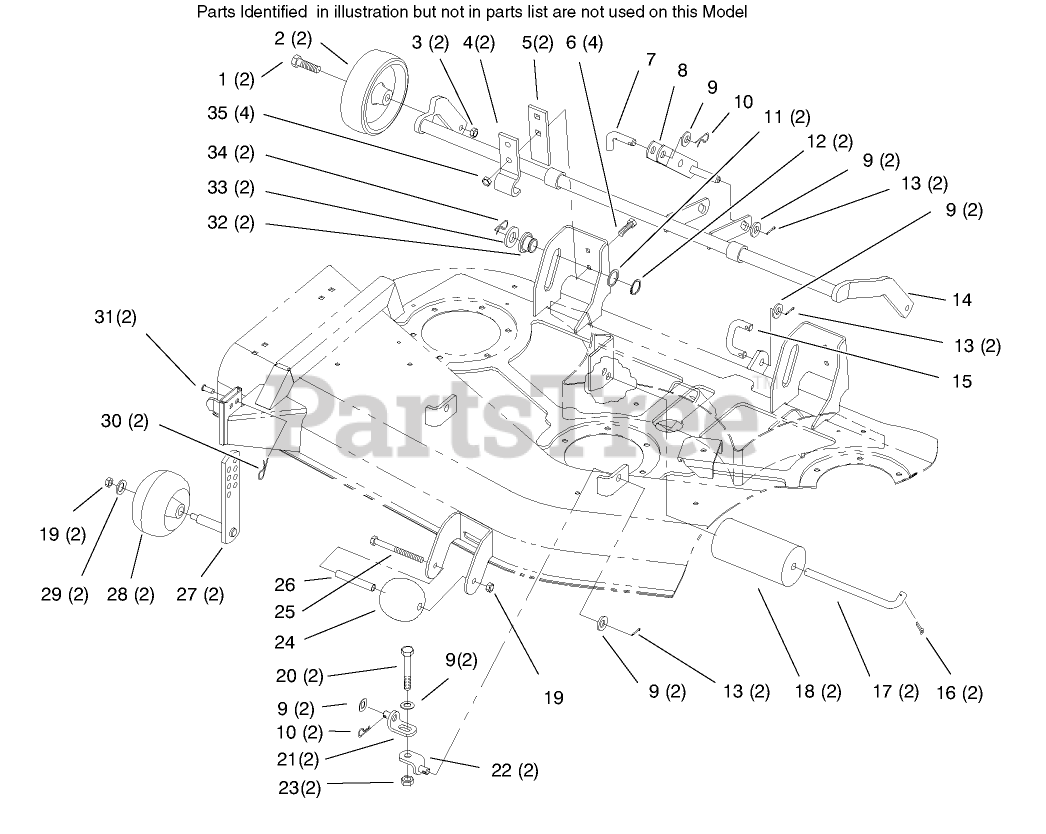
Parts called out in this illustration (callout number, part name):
1	BOLT-SHOULDER
2	WHEEL
6	SCREW-HH
7	PIN-LINK
8	LIFT ARM ASSEMBLY
9	WASHER-FLAT
10	PIN-COTTER, HAIR
11	WASHER-FLAT
12	RING-RETAINING
13	PIN-COTTER
15	LINK - REAR
16	PIN-COTTER
17	SHAFT-ROLLER, REAR
18	ROLLER-DECK
19	NUT-LOCK, NI
20	SCREW-HH
21	BRACKET-LIFT, LOWER
22	BRACKET-LIFT, UPPER
23	NUT-JAM
24	ROLLER
25	SCREW-HH
26	TUBE-SPACER, WHEEL
27	GAGE-WHEEL
29	WASHER-FLAT
30	PIN-HAIR
31	PIN-CLEVIS
32	ROLLER-LIFT
33	WASHER-FLAT
34	PIN-HAIR
35	NUT-HF
